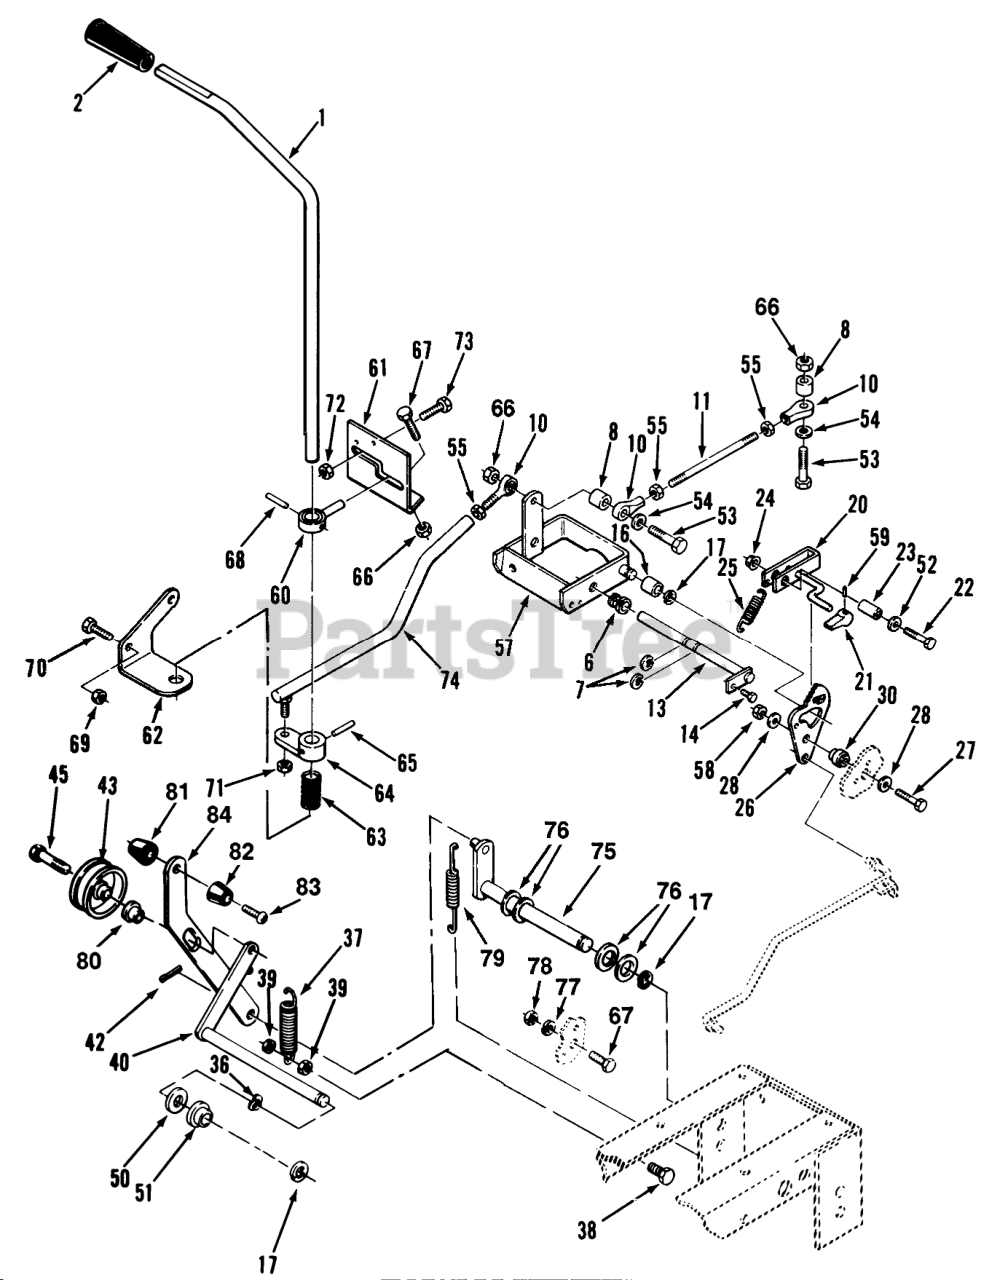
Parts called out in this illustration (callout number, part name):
1	ROD-MOTION CONTROL
2	Knob-Motion Control
6	NYLINER BUSHING
7	E Ring
8	Spacer
10	ROD END, 1/4-28
11	ROD-CONTROL
13	ASSY-ROD CAM PIVOT
14	SCREW
16	BEARING-CAM RETURN
17	E Ring
20	Lever-Parking Brake
21	KNOB-PARKING BRAKE
22	Bolt
23	SPACER
24	LOCKNUT-FLANGE
25	Spring
26	Cam Plate
27	BOLT
28	Washer
30	Spacer
36	WASHER-WAVE
37	SPRING-EXTENSION
38	Bolt
39	Nut
40	ASSY-ARM/ROD WA
43	PULLEY-IDLER
45	BOLT-SPECIAL HEX
50	Washer
51	BUSHING-FLANGED
52	Washer
55	Jam Nut 1/4-28
57	Cam Comtrol
58	NUT
59	PIN-SPIROL 3/32X5/8
60	GUIDE-CONTROL
61	Bracket-Control
62	Bracket-Control
63	SPRING-COMPRESSION
64	ARM-CONTROL
65	Spirol Pin
66	Nut
67	Bolt
68	SPIROL PIN 7/32X7/8
69	Nut
70	Bolt
71	5/16-24 E.S. NUT
72	Nut
73	Bolt
74	ASSY-ROD & BALL JOINT
75	ASSY-BRAKE LEVER
76	Washer
77	LOCKWASHER
78	Nut
79	SPRING-EXTENSION
80	SPACER-BRAKE LINK
81	KNOB
82	KNOB
83	BOLT-4
84	Handle
